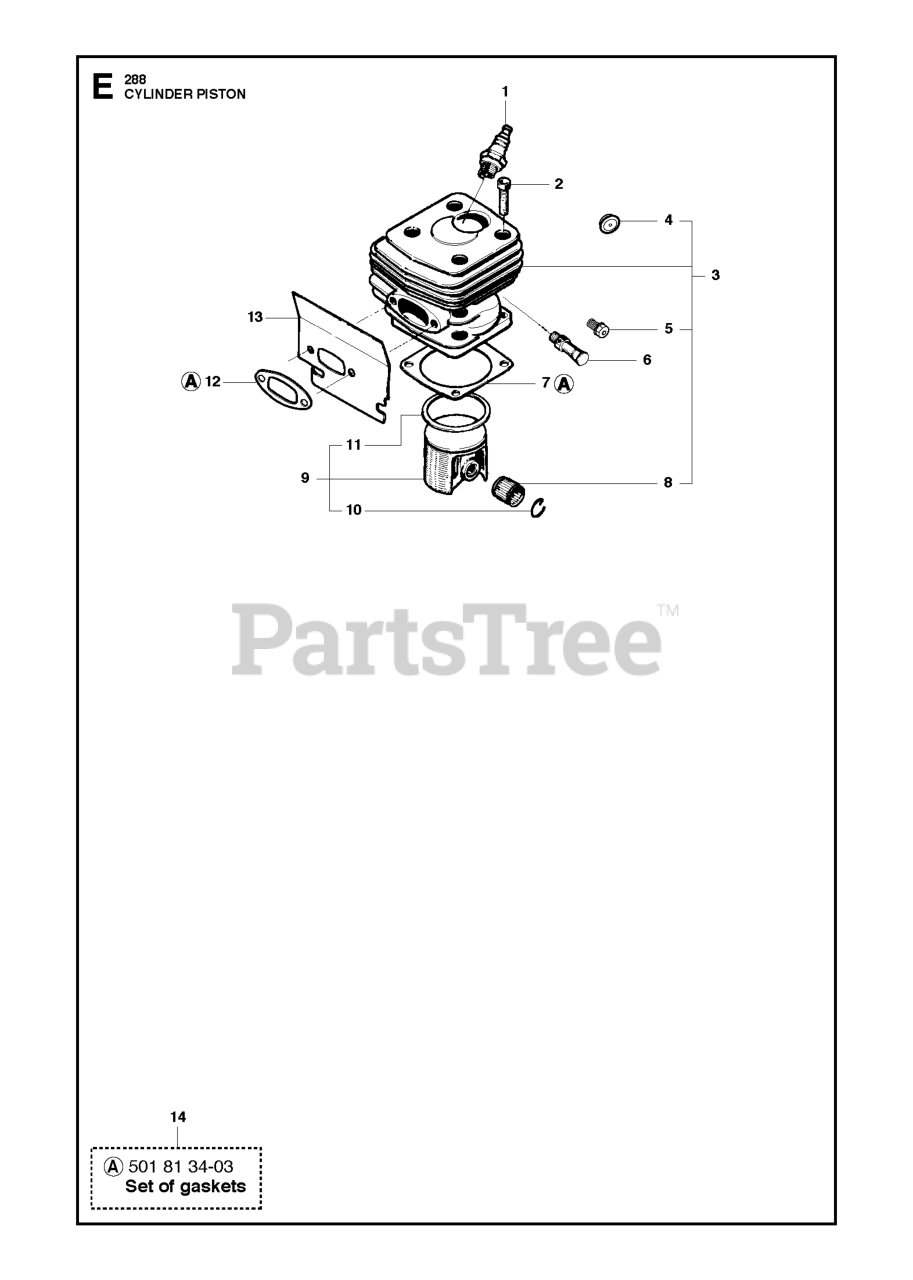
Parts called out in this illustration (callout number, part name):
1	SPARK PLUG RCJ6Y NLA
3	CYLINDER ASSY
5	CYLINDER PLUG
6	DECOMPRESSION VALVE
8	SUPPORT BUSHING
9	PISTON ASSY
11	PISTON RING
14	GASKET KIT
